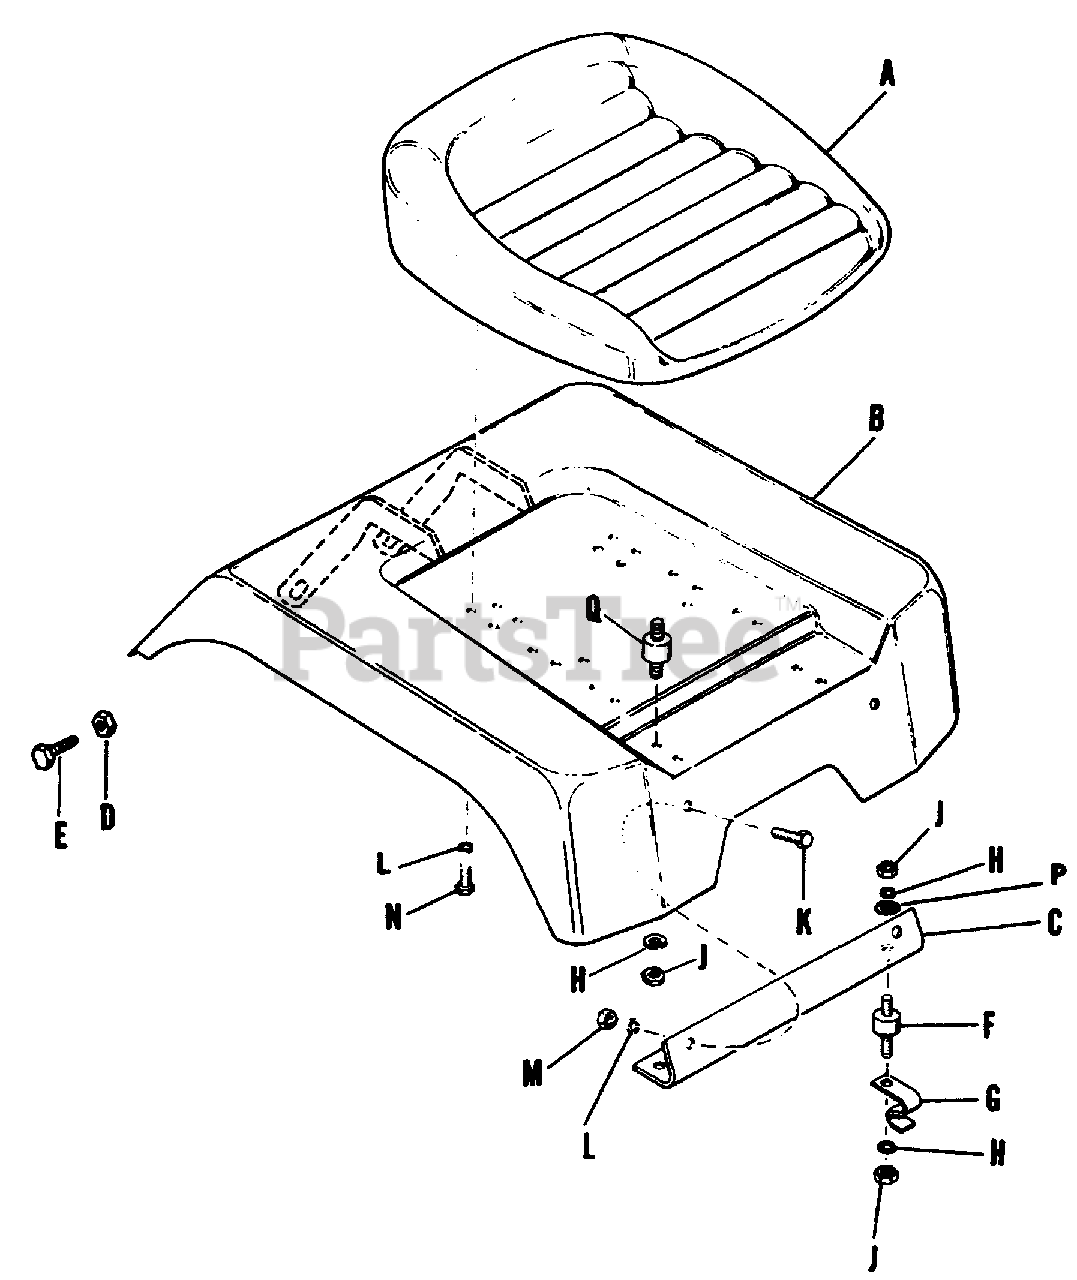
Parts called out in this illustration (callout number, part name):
A	Seat Assembly
B	Seat Deck Assembly
C	Seat Deck Bracket, Front
D	Hex. Locknut, Full, 3/8"-16
E	Hex Head Capscrew, 3/8"-16 x 1-1/4"
F	Cushion Connector, Front
G	Spring Clip
H	Lock Washer, 5/16"
J	Hex. Nut. Full, 5/16"-18
K	Hex. Head Capscrew, 5/16"18 x 5/8" lg.
L	Lockwasher, 5/16"
M	Hex. Nut, Full, 5/16"-18
N	Hex. Head Capscrew, 5/16"-18 x 5/8" lg.
P	Plain Washer 1/4"
Q	Cushion Connector, Front
